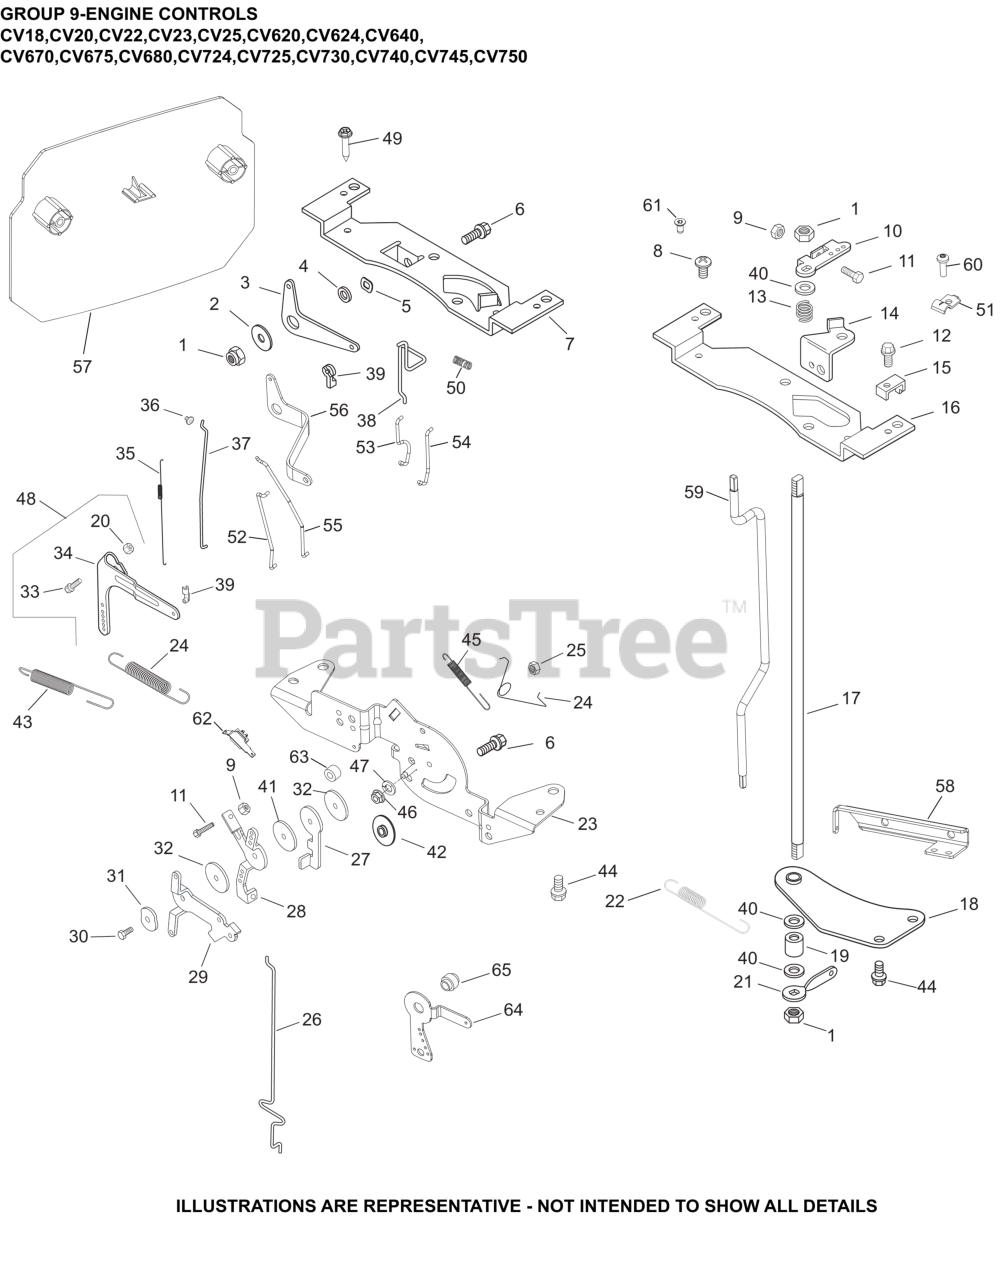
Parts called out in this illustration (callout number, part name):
1	NUT, LOCK M6X1.0
2	WASHER, FLAT 1/4"
5	WASHER, SPRING 3/8"
6	SCREW, FLG M6X1.0X16
7	BRACKET, CONTROL
9	NUT, M4X0.7
10	LEVER, THROTTLE CONTROL
11	SCREW, CAP M4X.7X30
12	SCREW, THREAD FORMING
12	SCREW, HI-LOW
13	SPRING, THROTTLE SHAFT
15	CLAMP, CABLE-(#2523753S)
18	BRACKET, THROTTLE SHAFT
20	NUT, FLG M6X1.0
21	LEVER, THROTTLE CONTROL
22	SPRING, GOVERNOR (BLACK)
33	BOLT, RD HD SQ NECK M6X1.0X25
34	LEVER, GOVERNOR - (#2409069S)
35	SPRING, LINKAGE
36	BUSHING, LINKAGE RETAINING
37	LINKAGE, THROTTLE
39	BUSHING, THROTTLE LINKAGE
40	WASHER, FLAT 1/4"
43	SPRING, GOVERNED IDLE
48	LEVER, GOVERNOR ASSEMBLY
53	LINKAGE, CHOKE
56	LEVER, CHOKE
58	BRACKET, GOVERNED IDLE
59	SHAFT,CONTROL
